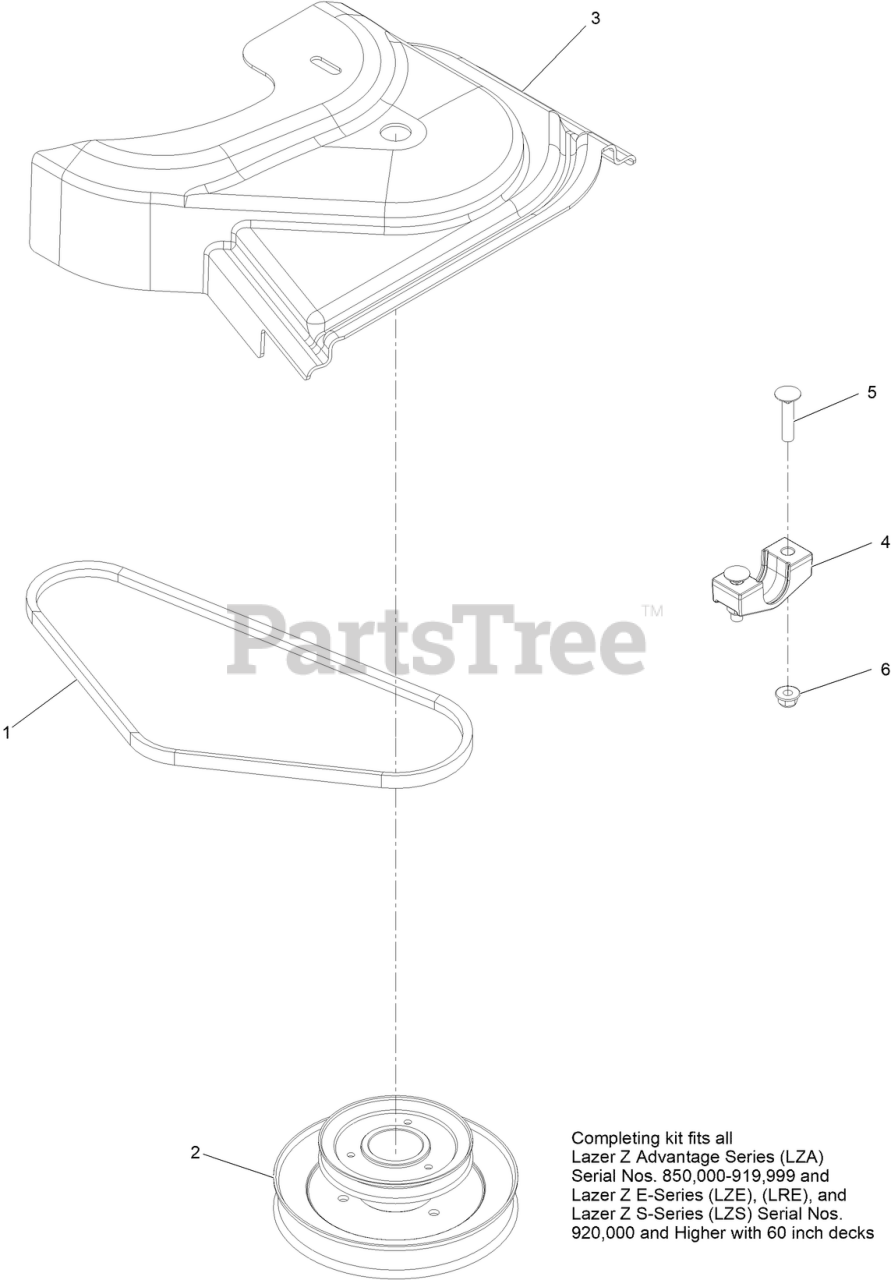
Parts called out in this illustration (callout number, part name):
2	JACKSHAFT,UV DRIVE 604 SPLINED
3	COVER,BELT UV 60
4	SUPPORT-BEARING CROSS SHAFT
5	SCREW-CARR
6	NUT-HF, NI
